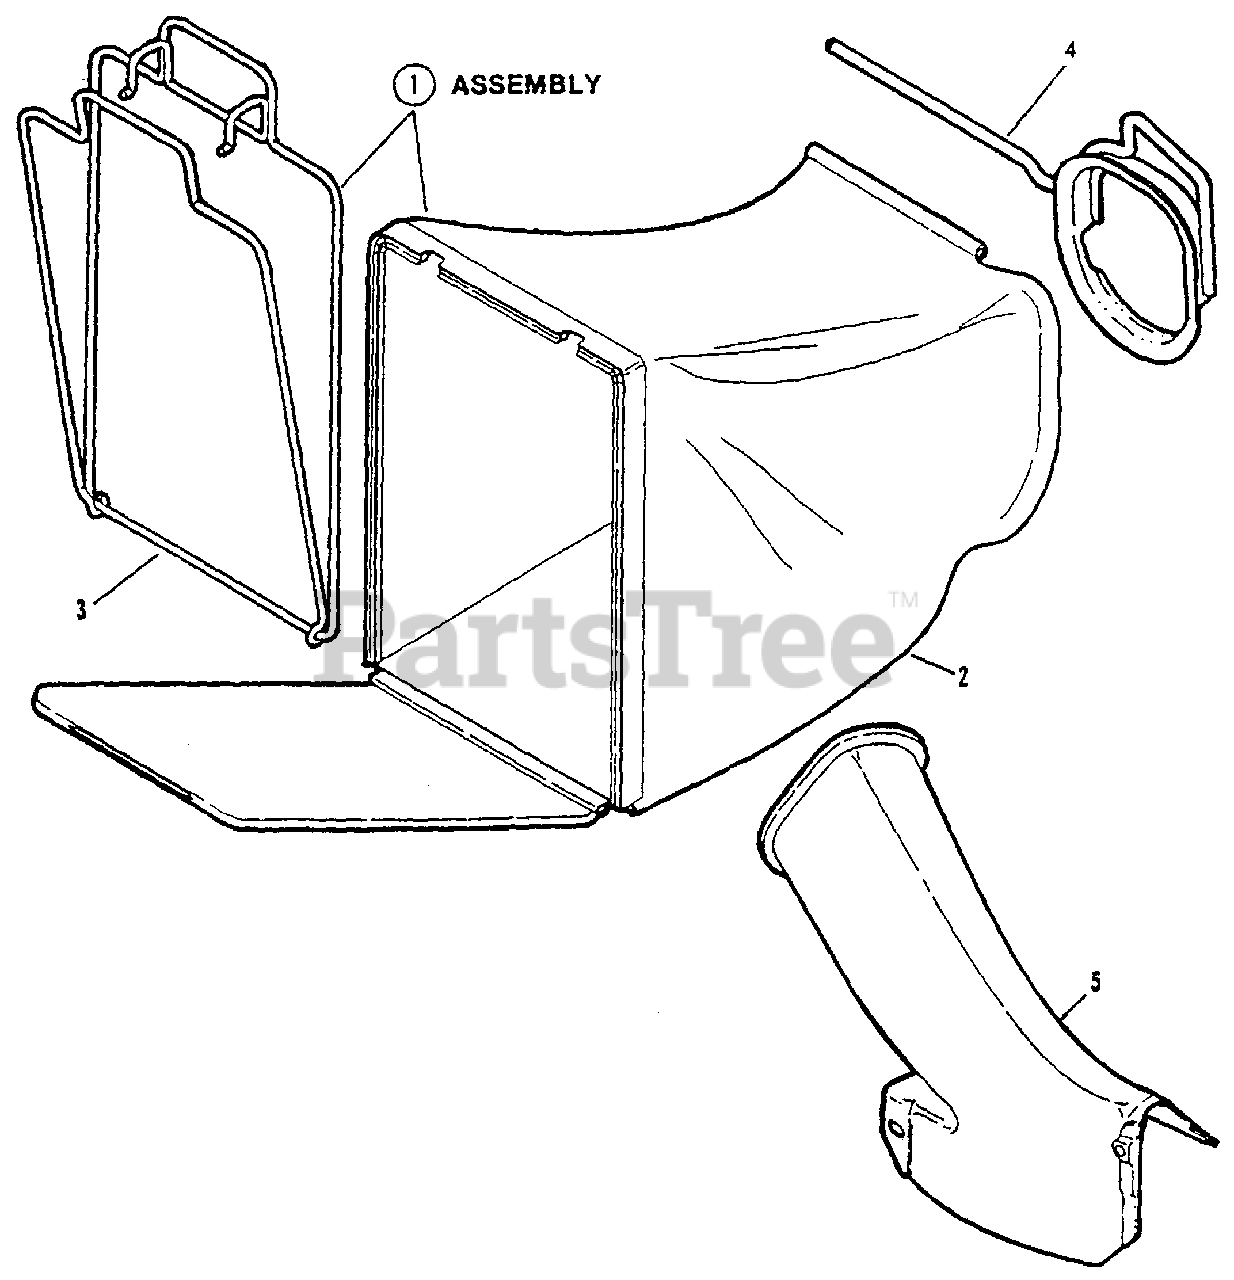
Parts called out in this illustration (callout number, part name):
1	ASSEMBLY, Grass Bag
2	BAG, Door Type (Wide) (Black)
3	ASSEMBLY, Bag Wire
4	CONNECTOR, Grass Bag
5	ADAPTER, Bag
